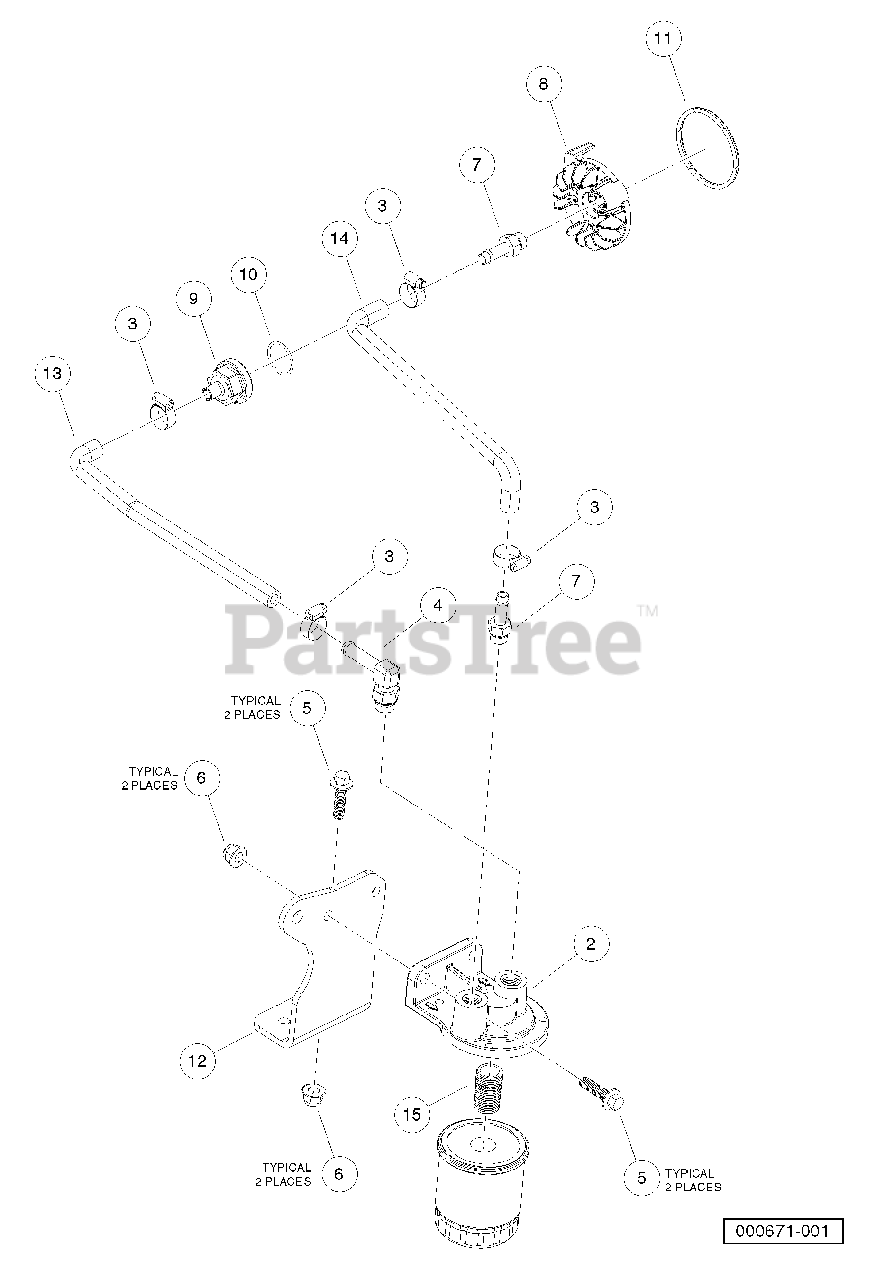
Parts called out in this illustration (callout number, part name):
2	Bracket, Oil Filter Mount
3	Clamp, Hose
4	Adapter, 90, 3/8 Tube
5	Bolt Flg, M8 X 1.25 X 30
6	Lock Nut, Flg M8 X 1.25 Nylon
7	Adapter, 5/16 Hose
8	Adapter, Special, Oil Filter
9	Nut, Special, Hose Adapter
10	O-ring, 23.52 X 1.78mm
11	O-ring, Oil Filter Adapter
12	Bracket, Oil Filter, Fh680d
13	Hose, Formed, Oil, 5/16"
14	Hose, Formed, Oil, 5/16", Ret
15	Nipple, 3/4-16 X M20 X 1.5-6g
